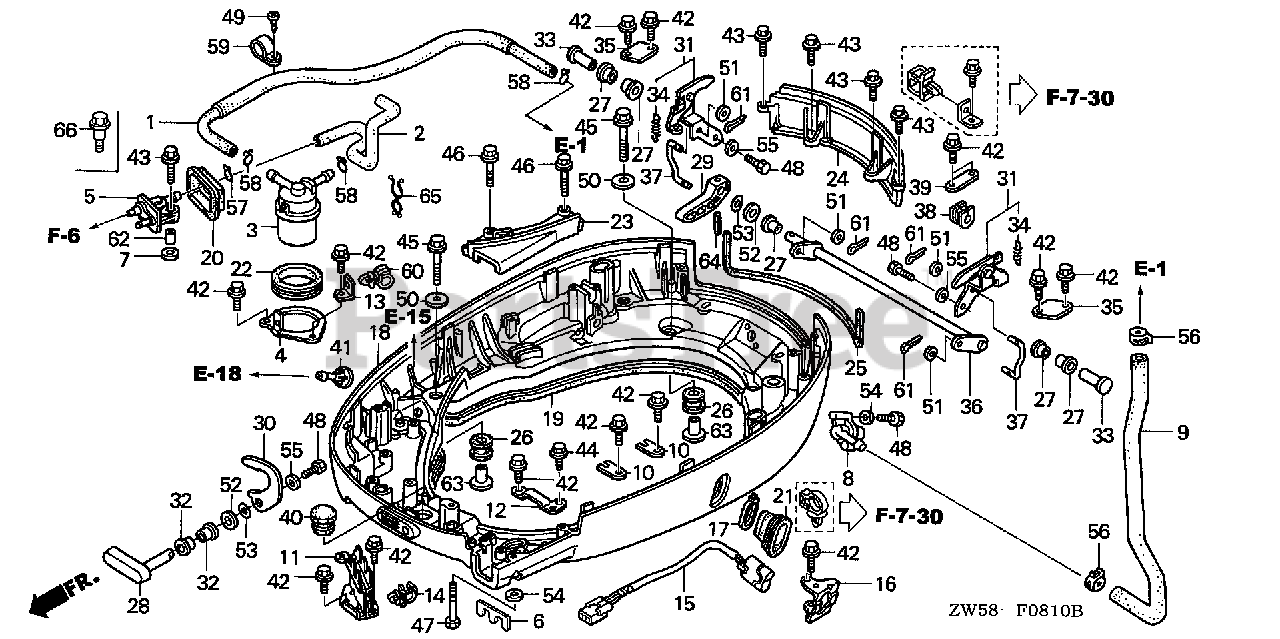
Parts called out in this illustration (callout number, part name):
1	TUBE, FUEL
2	TUBE B, FUEL
3	FILTER, FUEL
4	STAY, FUEL STRAINER
5	CONNECTOR ASSY., FUEL (B)
6	PLATE, REMOTE CONTROL CABLE
7	WASHER, PIVOT
8	JOINT, WATER INLET
9	HOSE, FLUSHING WATER
10	PLATE, SHIFT SHAFT
11	BRACKET, CONNECTOR (B)
12	BRACKET, CABLE CLIP (S)
13	BRACKET, CLIP (C)
14	CLAMP, WIRE
15	SWITCH ASSY., POWER TRIM-TILT
16	STAY, POWER TILT SWITCH
17	BAND (BLACK 3.5X140)
18	CASE, ENGINE (LOWER) *NH282MU* (OYSTER SILVER METALLIC-U)
19	SEAL, CASE (LOWER)
20	GROMMET, CASE (LOWER) (B)
21	GROMMET, CASE (LOWER) (G)
22	GROMMET, FUEL STRAINER
23	CASE, SEPARATE *NH282MU* (OYSTER SILVER METALLIC-U)
24	CASE, RR. SEPARATOR *NH282MU* (OYSTER SILVER METALLIC-U)
25	SEAL, SEPARATOR CASE
26	RUBBER, FR. CARRIER CUSHION
27	BUSH (14X10)
28	LEVER, COVER LOCK *NH282MU* (OYSTER SILVER METALLIC-U)
29	LEVER, COVER LOCK
30	HOOK, COVER LOCK
31	HOOK, COVER LOCK
32	BUSH, COVER LOCK
33	SHAFT, COVER B LOCK
34	SPRING, COVER LOCK HOOK
35	PLATE, COVER LOCK SHAFT
36	SHAFT, COVER LOCK
37	ROD, COVER LOCK
38	BUSH, COVER LOCK SHAFT
39	PLATE, COVER B LOCK SHAFT
40	CAP, L. SIDE COVER
41	GROMMET, WATER CHECK
42	BOLT, FLANGE (6X12) (CT200)
43	BOLT, FLANGE (6X20) (CT200)
44	BOLT, FLANGE (5X10) (CT200)
45	BOLT, FLANGE (8X35)
46	BOLT, FLANGE (6X30)
47	BOLT, HEX. (6X40)
48	BOLT, HEX. (6X16)
49	SCREW, RIVET (5X10)
50	WASHER, PLAIN (8MM)
51	WASHER, PLAIN (5MM)
52	WASHER (14MM)
53	WASHER, WAVE (14MM)
54	WASHER, PLAIN (6MM)
55	WASHER (6MM)
56	CLAMP, TUBE (D18.8)
57	CLIP, TUBE (B10)
58	CLIP, TUBE (B12)
59	CLIP (14MM)
60	CLIP, HARNESS
61	PIN, SPLIT (2.0)
62	COLLAR, DISTANCE (6MM)
63	COLLAR (8.5X14.5)
64	PIN, SPRING (6X22)
65	CLIP, PURSE LOCK
